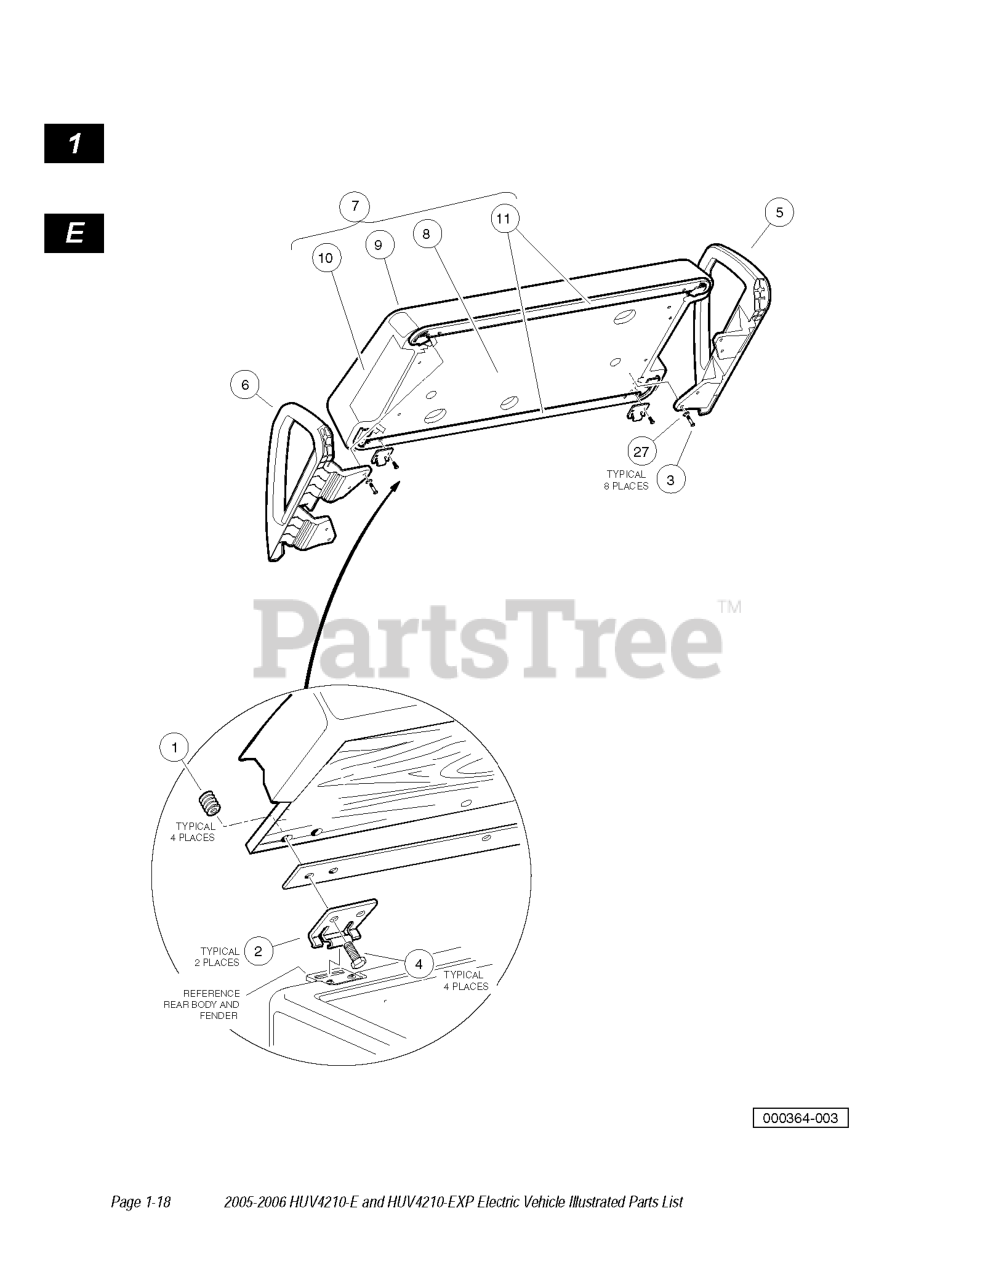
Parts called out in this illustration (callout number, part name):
1	INSERT - WOOD
2	HINGE PLATE
3	SCREW, 1/4-20 X 1.50 HX HD CAP
4	SCREW, 1/4-20 X .750 HEX HEAD
5	ARMREST, RH, DEBADGED
6	ARMREST, LH, DEBADGED
7	SEAT ASSEMBLY-BUFF
9	Vinyl Cover, Seat Bottom, Buff
11	GASKET, SEAT
12	Seat Bottom Assembly, White
14	Vinyl Cover, Seat Bottom, White
16	GASKET, SEAT
17	Seat Bottom Assembly, Black
19	Vinyl Cover, Seat Bottom, Black
21	GASKET, SEAT
22	SEAT ASSEMBLY GRAY
24	GRAY VINL COVER SEAT
26	GASKET, SEAT
27	WASHER 1/4 FLAT
